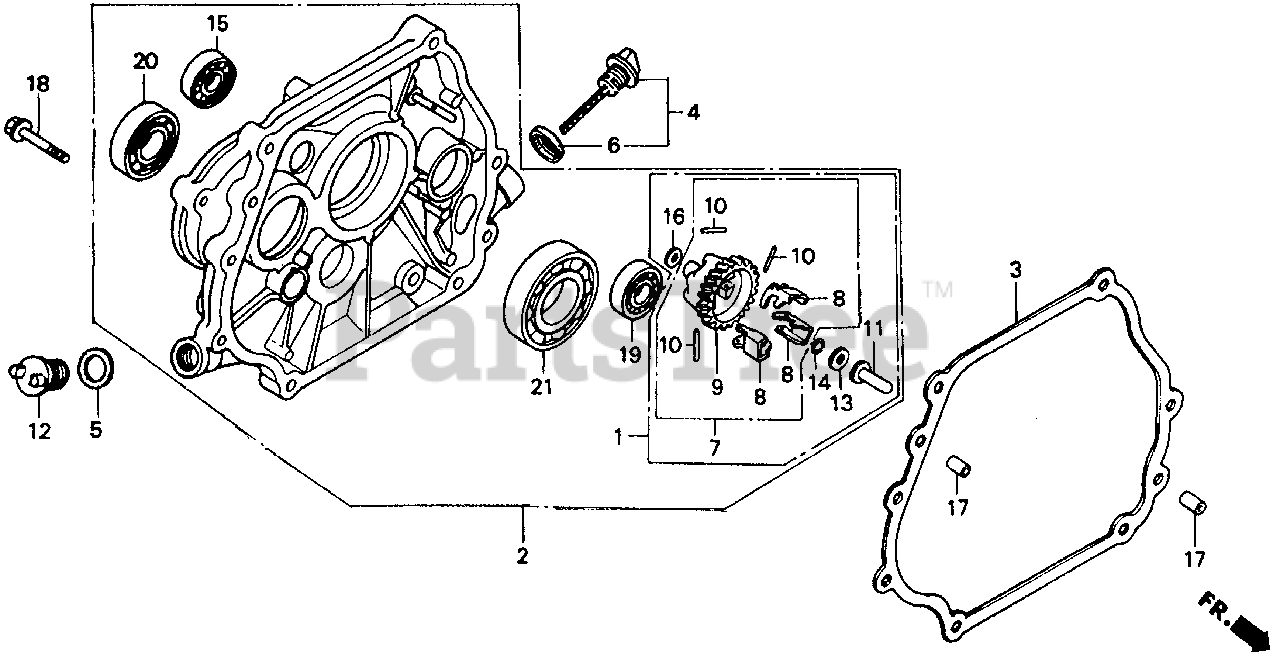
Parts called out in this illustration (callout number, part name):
1	GOVERNOR KIT
2	COVER ASSY., CRANKCASE (L-TYPE) (NOT AVAILABLE)
2	COVER ASSY., CRANKCASE (L-TYPE)
3	GASKET, CASE COVER
4	CAP ASSY., OIL FILLER
5	GASKET, OIL FILLER CAP
6	GASKET, OIL FILLER CAP
7	GOVERNOR ASSY.
8	WEIGHT, GOVERNOR
9	HOLDER, GOVERNOR WEIGHT
10	PIN, GOVERNOR WEIGHT
11	SLIDER, GOVERNOR
12	CAP, OIL FILLER
12	CAP, OIL HOLE
13	WASHER (6X16)
14	CLIP, GOVERNOR HOLDER
15	BEARING, RADIAL BALL (6202)
16	WASHER, PLAIN (6MM)
17	PIN, DOWEL (8X12)
17	PIN A, DOWEL (8X12)
17	PIN A, DOWEL (8X14)
18	BOLT, FLANGE (8X40)
19	BEARING, RADIAL BALL (6202)
20	BEARING, RADIAL BALL (6204)
21	BEARING, RADIAL BALL (6207)
